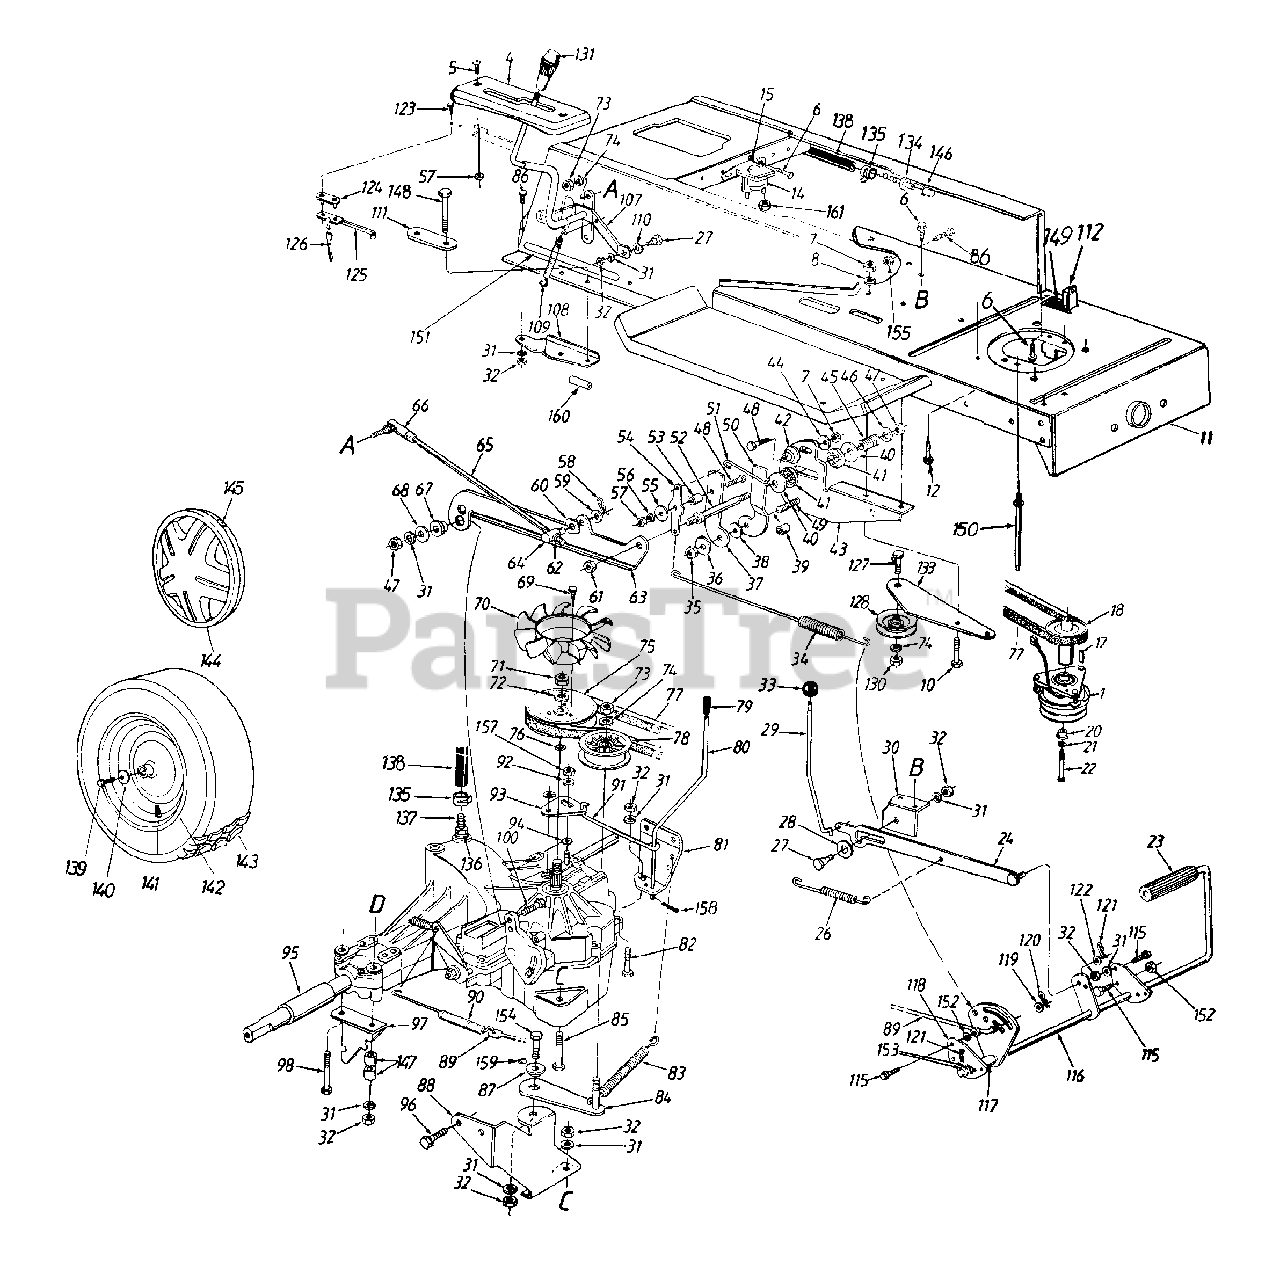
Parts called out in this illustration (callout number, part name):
1	Electric Clutch
4	Index Bracket
5	Pan Hd. Mach. Scr. 1/4-20 x .75" Lg.
6	Hex Washer TT-Tap Scr. 1/4-20 x .5" Lg.
7	Hex Nut 1/4-28 Thd.
8	L-Wash. 1/4" I.D.
10	Hex Bolt 1/4-20 x .75" Lg.
12	Hex Tap Scr. 3/8-16 x 1.25" Lg.
14	Solenoid
15	Ext. L-Wash. 1/4" I.D.
17	Sq. Key 1/4" x 1.5" Lg.
18	Engine Pulley
20	Fl. Wash. .450 x 1.5 x 1.72
21	L-Wash. 7/16" I.D.
22	Hex Bolt 7/16-20 x 3.25" Lg.
23	Foot Pad
27	Shld. Bolt .437" Dia. x .268"
28	Fl-Wash. 7/16" I.D. x 1-3/8" O.D.
29	Lock-up Rod
31	L-Wash. 5/16" I.D.
32	Hex Nut 5/16-18 Thd.
34	Neutral Return Spring
35	Hex Nut 5/16-24 Thd.
36	Fl-Wash. .349" I.D. x .879 x .63
37	Scissor-Flat
38	Fl-Wash. .565" I.D. x 1.12" O.D. x .06
40	Bell-Wash. .4" I.D. x 1.13" O.D.
41	Friction Washer
42	Centering Gauge Spacer
43	Neutral Return Mtg. Brkt.
44	Bell-Wash. .265" I.D. x .75" O.D.
45	Comp. Spring 1.19" Lg.
46	Fl-Wash. .312" I.D. x .75" O.D.
47	Hex Nut 5/16-24 Thd.
48	Hex Bolt 1/4-28 x 1" Lg. (Gr. 5)
49	Rib Neck Bolt 5/16-24 x .84" Lg.
50	Scissor-Offset
51	Neutral Return Rod
52	Friction Disc Stud
53	Shld. Spacer
54	Neutral Return Lever
55	Fl-Wash. .265" I.D. x 1" O.D.
57	Hex Nut 1/4-20 Thd.
58	Hairpin Clip
59	Fl-Wash. .375" I.D. x .87" O.D.
60	Spring Wash. .39" I.D.
61	Hex L-Nut 3/8-24 Thd.
62	Hex Jam Nut 3/8-24 Thd.
63	Neutral Return Brkt.
64	Ferrule 3/8-24 Thd.
65	Control Rod
66	Ball Joint 3/8-24 Thd.
67	Shld. Spacer .5" Dia. x .27" Lg.
68	Fl-Wash. .349" I.D. x .879" O.D.
69	Hex Wash. Hd. Tap Scr. #12 -24: .625
70	Fan
71	Hex Nut 1/2-20 Thd.
72	L-Wash. 1/2" I.D.
73	Hex Nut 3/8-24 Thd.
74	L-Wash. 3/8" I.D.
75	Transmission Pulley
77	"V"-Belt
78	Fl-Idler Pulley 2.75" O.D.
79	Rod End Grip
80	Bypass Control Lever
83	Ext. Spring 6.12
86	Hex Bolt 5/16-18 x .75" Lg.
87	Shld. Spacer .5" Dia. x .27" Lg.
90	Ext. Spring
91	Bypass Actuator Rod
92	Fl-Wash. .281" I.D. x .5" O.D.
93	Bypass Adjustment Brkt.
94	External L-Wash. 1/4" I.D.
95	Sleeve .758" I.D. x 1" O.D.
96	Hex Wash. TT-Tap Scr. 5/16-18 x .62" Lg.
100	Hex Bolt 5/16-24 x 1" Lg.
107	Speed Control Lever Ass'y.
110	Spr.-Wash. .445" I.D. x .75" O.D.
112	Safety Switch (Clutch)
115	Hex Wash. Scr. 5/16-18 x .75" Lg.
120	Cotter Pin 3/32" Dia.
121	Cotter Pin 1/8" Dia.
122	Fl-Wash. .385" I.D. x .62" O.D. .06
123	Hex Wash. Hd. AB-Tap Scr. #8 x .5" Lg.
124	Insulator Nut Plate
125	Spring Switch
126	Extension Wire
127	Hex Bolt 3/8-16 x 1.5" Lg.
128	Idler Pulley
130	Hex Nut 3/8-16 Thd.
135	Clamp
137	Hose Fitting
138	Fuel Line 18" Lg.
139	Hex Bolt 5/16-24 x .75" Lg.
140	Bell-Wash. .345" I.D. x .88" O.D.
141	Air Valve
145	Spring Clip
148	Hex Bolt 5/16-18 x 3.5" Lg.
149	Spring Switch
150	Belt Guard Pin
151	Brkt - S.P. Control Reinforcement
152	Hex Nut 5/16-18
153	Lock Washer 3/8
154	Hex Screw 5/16-18:1"
158	Cotter Pin 1/16 x .75
160	Spacer
